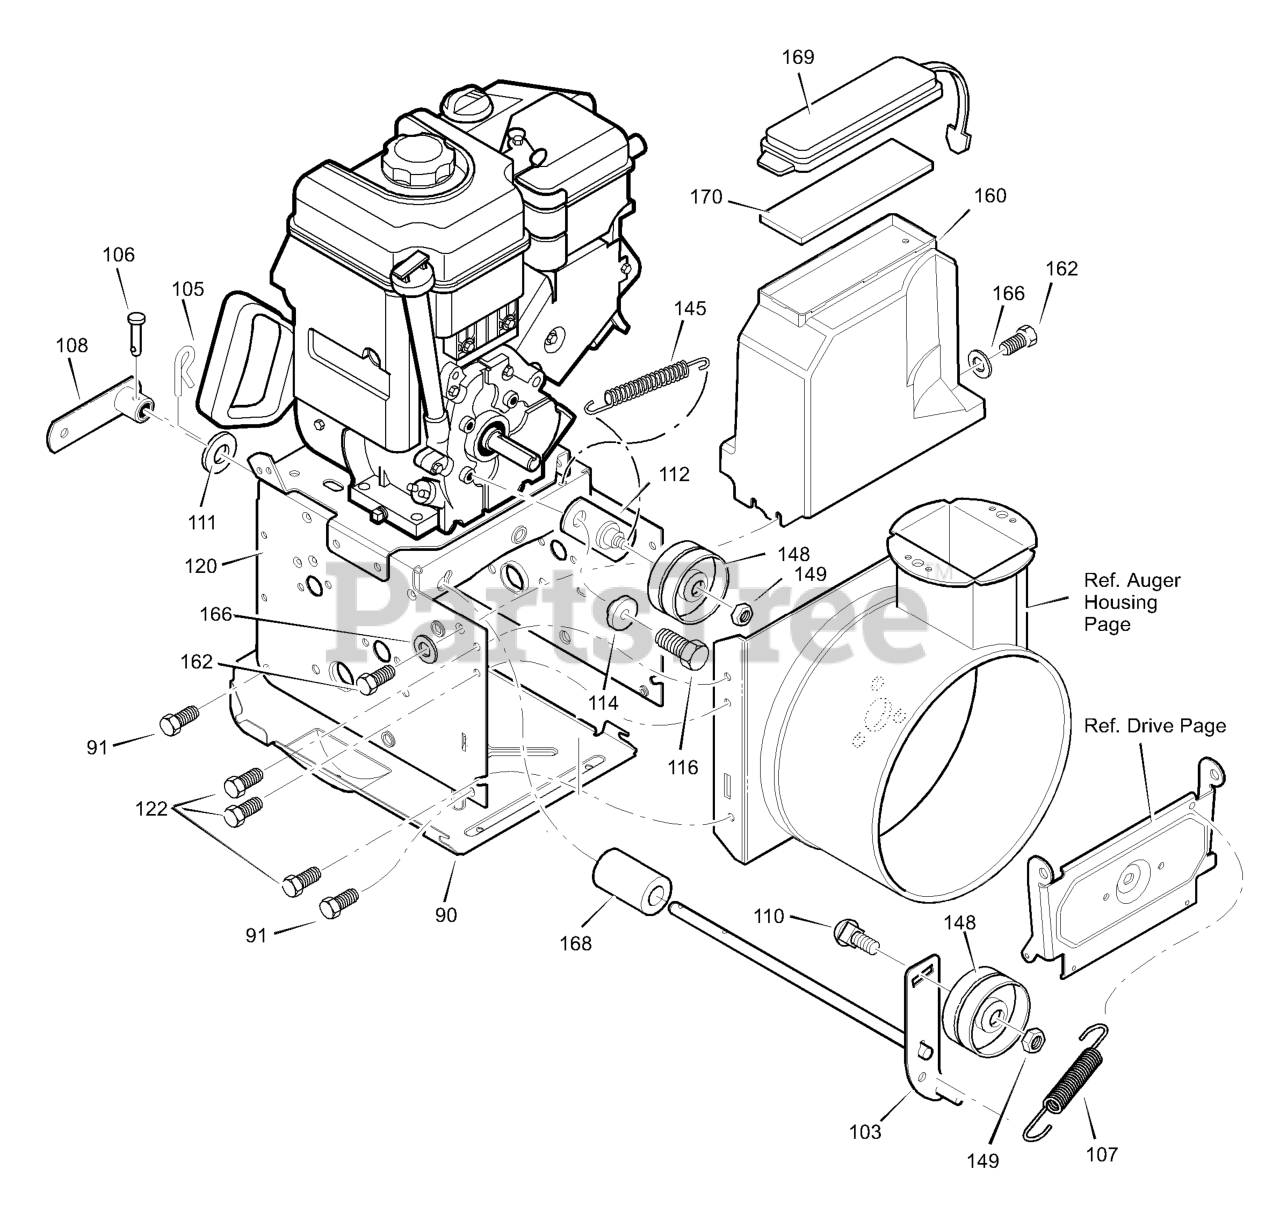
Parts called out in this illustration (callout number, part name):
90	COVER, BOTTOM
91	SCREW
103	IDLER, AUGER
105	PIN, HAIR
106	PIN, CLEVIS
107	SPRING, TENSION
108	ATTACH, SPRING
110	BOLT, CARR.
111	WASHER, FLAT
112	BRACKET, IDLER
114	BUSHING, IDLER
118	WASHER, SPLIT
122	SCREW, TAP
145	SPRING, IDLER
148	PULLEY, IDLER
149	NUT, JAM
160	COVER, BELT
162	SCREW, TAP
166	WASHER, FLAT
168	SPACER, AUGER
169	LID, TOOL BOX
170	PAD, FOAM
